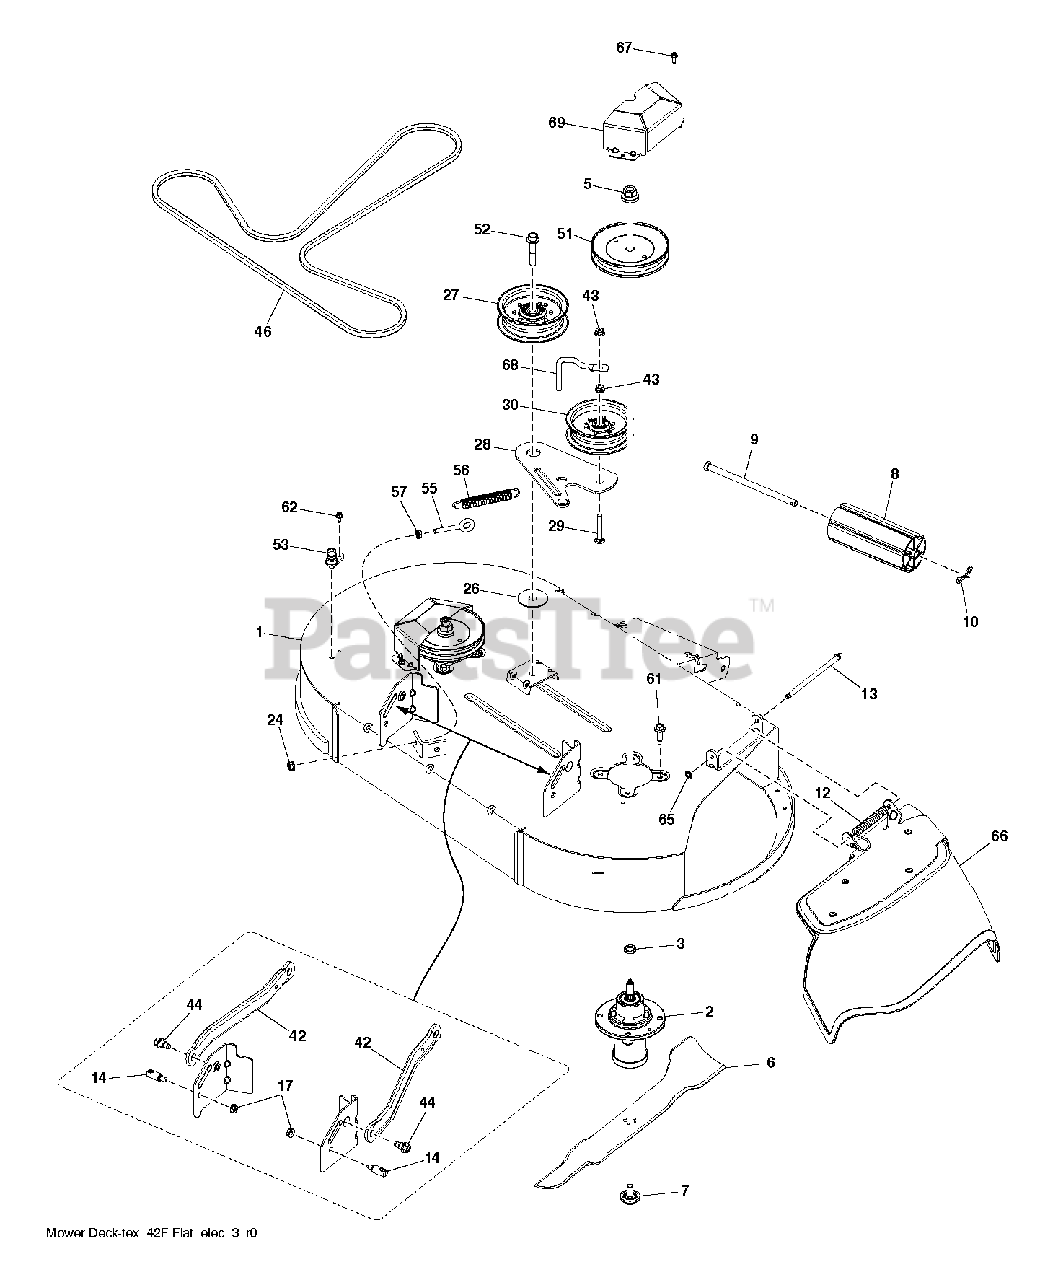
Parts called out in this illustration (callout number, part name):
1	HOUSING.ASM.PNT.42.FCS.WEL.TR
2	MANDREL.DECK.ASSEMBLY
3	WASHER.SPACER.MANDREL
5	LOCKNUT - 9/16
6	BLADE.42.FCS.BAGGING.BLADE.RAW
7	BOLT.WASHER.ASM.7/16-2
8	NOSE ROLLER 48"
9	ROD.ROLLER.NOSE.NARROW.48"
10	PIN.COTTER.5/16.BOW TI
12	SPRING.42.FCS.DEFLECTOR
13	ROD.HINGE
14	STUD.FASTNER.W/ANTI-ROTATE
17	NUT LOCK HEX FLANGE 5/16-18
24	5/16-18 NYLOC FLANGE NUT
27	PULLEY.IDLER.MWR.STATI.LH
28	ARM.42"FCS.CLUTCHING.X431
30	PULLEY.IDLER.2006
42	ARM.SUSPENSION.MOWER
43	NUT LOCK FLG 3/8-16 UNC
44	BOLT.SHOULDER
46	BELT.42.FCS.TRACTOR.DECK.DRIVE
51	PULLEY MANDREL 5.0"
52	SCREW.7/16-14 X 2.125.WASHER
53	PORT.WASHOUT
55	EYE BOLT 5/16 X 3.50
56	SPRING.EXTN.42.FCS.TR.DECK.DRV
57	NUT 5/16C WHIZ
61	BOLT.HEX.WASHR.HED.313-18X1.19
62	SCREW.TT.#10-32X.5.3/8.FLANGE
65	NUT PUSH M
66	DEFLECTOR.42".FCS
67	SCREW.1/4-20X5/8
68	KEEPER.BELT.IDLER.54"T
69	COVER.42".MANDREL.FCS.PNT.498
